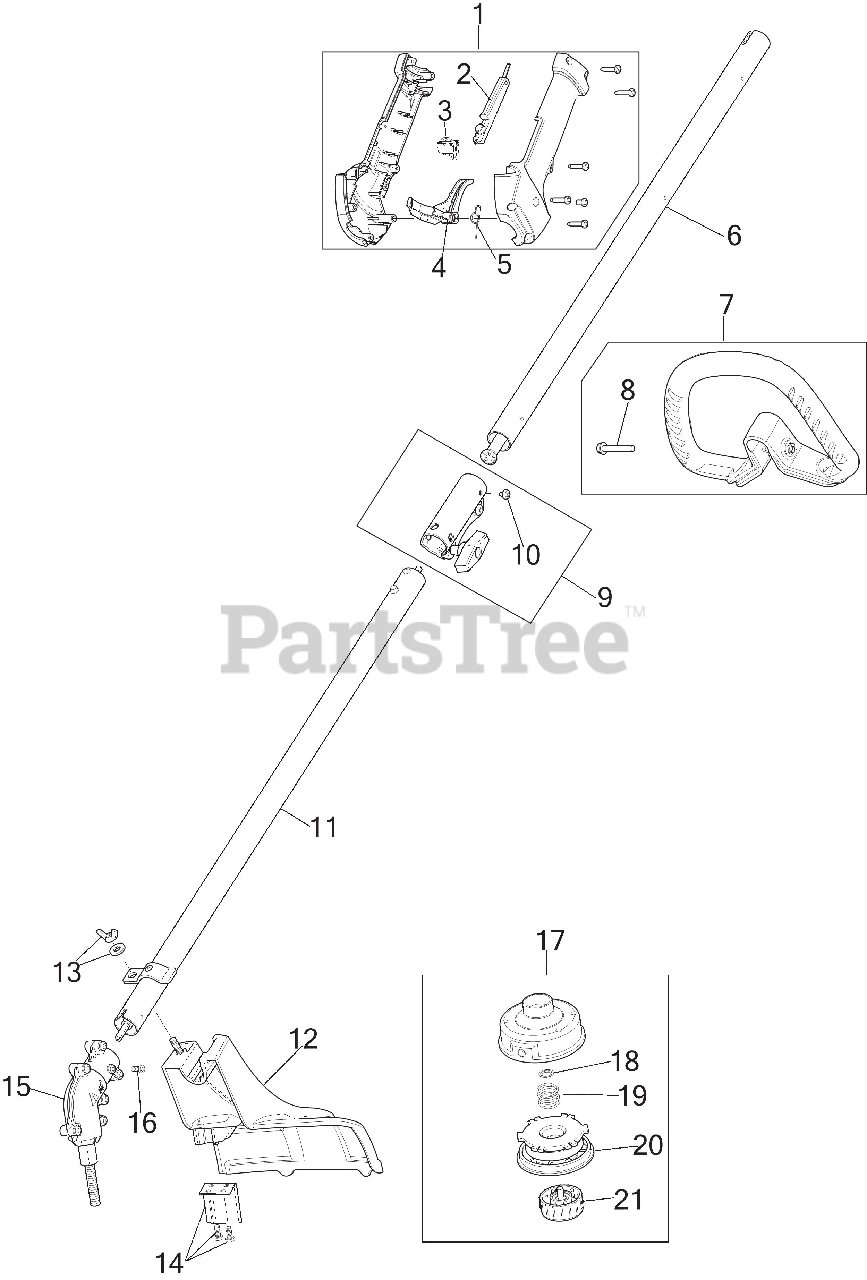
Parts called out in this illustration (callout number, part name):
1	THROTTLE GRIP ASSEMBLY
2	LOCK OUT LEVER
3	SW, MOMENTARY ON/O
4	THROTTLE TRIGGER
5	SPRING TRIG
6	BOOM ASSEMBLY UPR
7	HANLE ASSEMBLY
8	BOLT 1/4-20X1 1/2
9	E-Z LINK COUPLER
10	SCREW, 10-32X.250 TA
11	BOOM ASSEMBLY W/BRA
12	GUARD & BLADE ASSEMBLY
13	BLADE GUARD MOUNTING HARDWARE
14	BLADE ASSEMBLY W/HDW
15	GEARBOX ASSEMBLY
16	SCREW 8-32X.437
17	REEL:OTR W/RET
18	RETAINER .625 OD 2
19	SPRING-SPOOL
20	REEL-INNER SPOOL
21	BUMP HEAD KNOB ASSEMBLY
